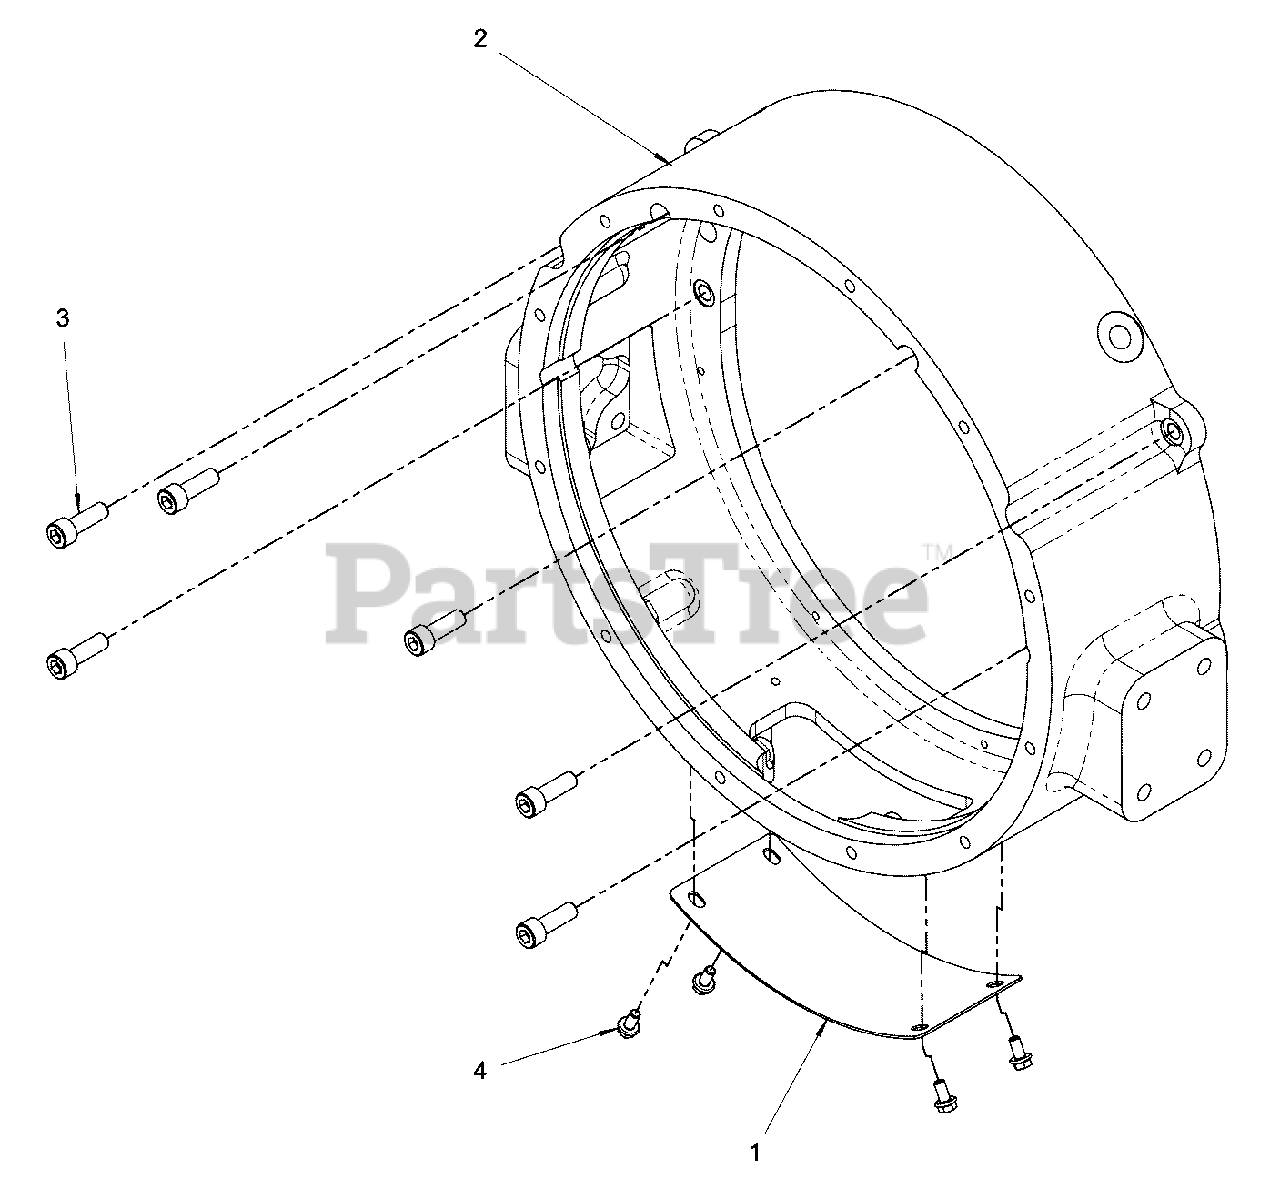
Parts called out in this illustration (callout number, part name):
1	COVER PLATE - B/W
3	BOLT
4	BOLT
